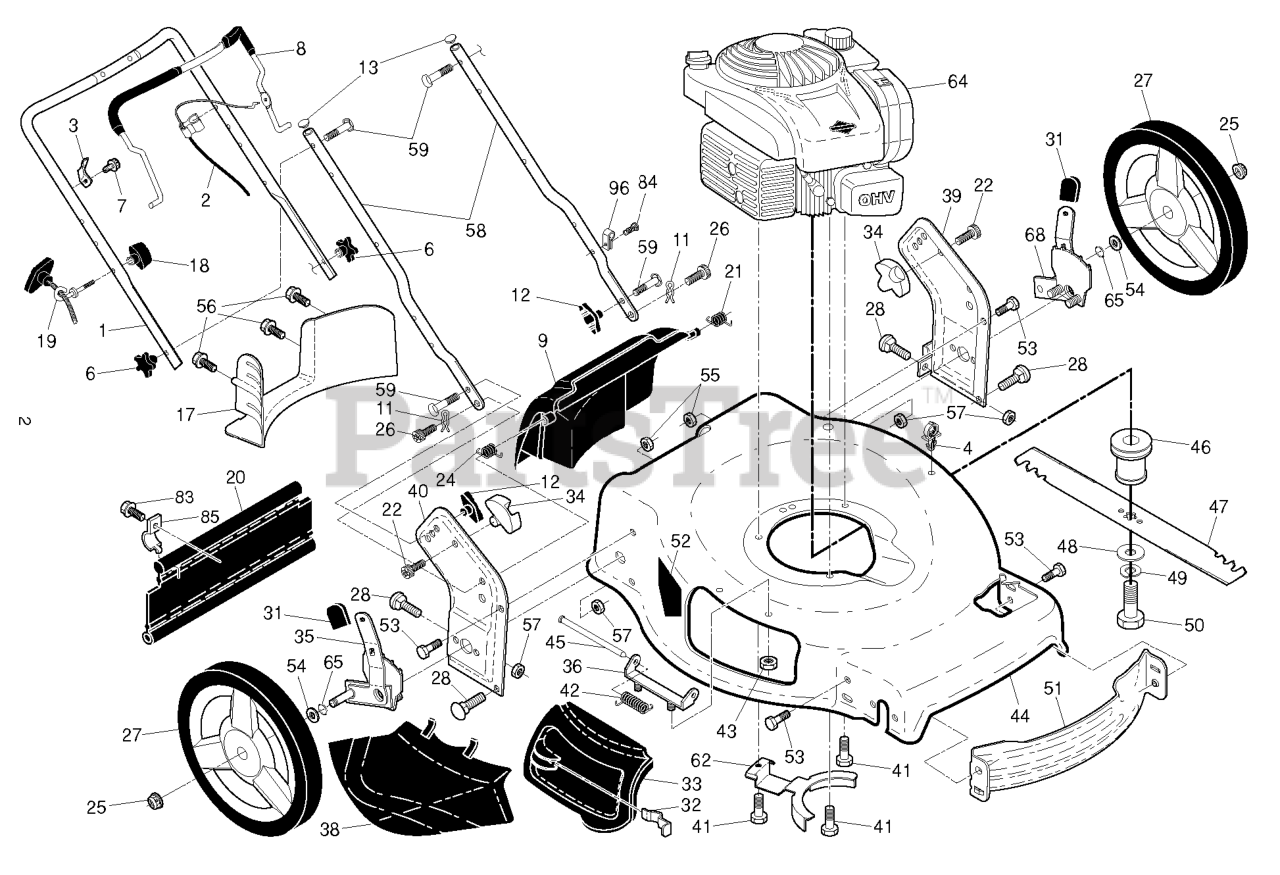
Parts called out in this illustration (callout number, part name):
1	HANDLE.UP.DST.SS/VS.FG/RG.NHGY
2	CABLE.MZR.FGD.PLUS
3	BRACKET.UPSTOP.RT
6	KNOB.HANDLE.PLASTIC.STAR.BLACK
8	BAIL.ARM.ASSY:STRAIGHT OM
9	DOOR.REAR.22PLUS.MB.FGD.GRY
11	COTTER.HAIRPIN.DOOR/HANDLE.PIV
12	KNOB, DEFLECTOR
13	PLUG.PLASTIC.7/8".14-20.GAUGE
17	BAFFLE.22PLUS.FGD.REAR.
18	T-KNOB.NEW ROPE GUIDE
19	GUIDE.ROPE.BLK.ZINC.CHROM
20	SKIRT.REAR.22PLUS.RGD/FGD.NEW
21	SPRING.LH.BLACK
22	SCREW.PAN.HEAD.#10
24	SPRING.RH.GRAY
25	NUT.HEX.FLANGE.3/8-16.LOCKNUT
26	SCREW,DOOR/HANDLE.PIVOT
27	WHEEL.12 X 1.75 CFH3SPK.RAD3
28	BOLT.CARRIAGE.LN.5/16-18X.5/8
31	SELECTOR KNOB
32	LATCH.DOOR.ZINC
33	DOOR.MULCH.22 PLUS.HUSQ.GREY
34	BRACKET.GRASSBAG.ATTACHING.BLK
35	ADJUSTER.ASM.9POS.HW.R/R
36	BRACKET.ASM.HINGE.21.FWGD.
38	DEFLECTOR.CLIPPING.22.BLACK
39	BRACKET.ASM.HANDLE.LT.22+.GREY
40	BRACKET.ASM.HANDLE.RT.22+.GREY
41	BOLT 3/8-16X1-1/8
42	SPRING.TORSION
43	NUT.HEX.FLANGE.1/4
44	HOUSING.22+.FWD.MC.ZWO.ORANGE.
45	ROD.HINGE.21
46	ADAPTOR.BLADE.7/8".STAR
47	BLADE.22PLUS
48	WASHER,HARDEN
49	LOCKWASHER
50	SCREW, HEX HD 3/8-24 X 1-3/8
51	BAFFLE.FRONT.22.PLUS
52	DANGER DECAL
53	BOLT.5/16HEX.WHS.HD
54	WASHER.FLAT.1/2
55	NUT.HEX.FLANGE.1/4
56	SCREW.HX.13X.750
57	NUT.FLANGE.5/16
58	HANDLE.LOWER.22+.BT.GRAY
59	BOLT, HANDLE 5/16-18X1.75
62	BRACKET.ENG/BELTKEEPER
65	O-RING..070X.487.NEOPRENE
68	ADJUSTER.ASM.9POS.HW.R/L
83	TAPPING SCREW
84	FASTENER.PUSH.O.250X0.783
85	BRACKET.SKIRT.22+.BZP
96	CLIP.CABLE.BLK
